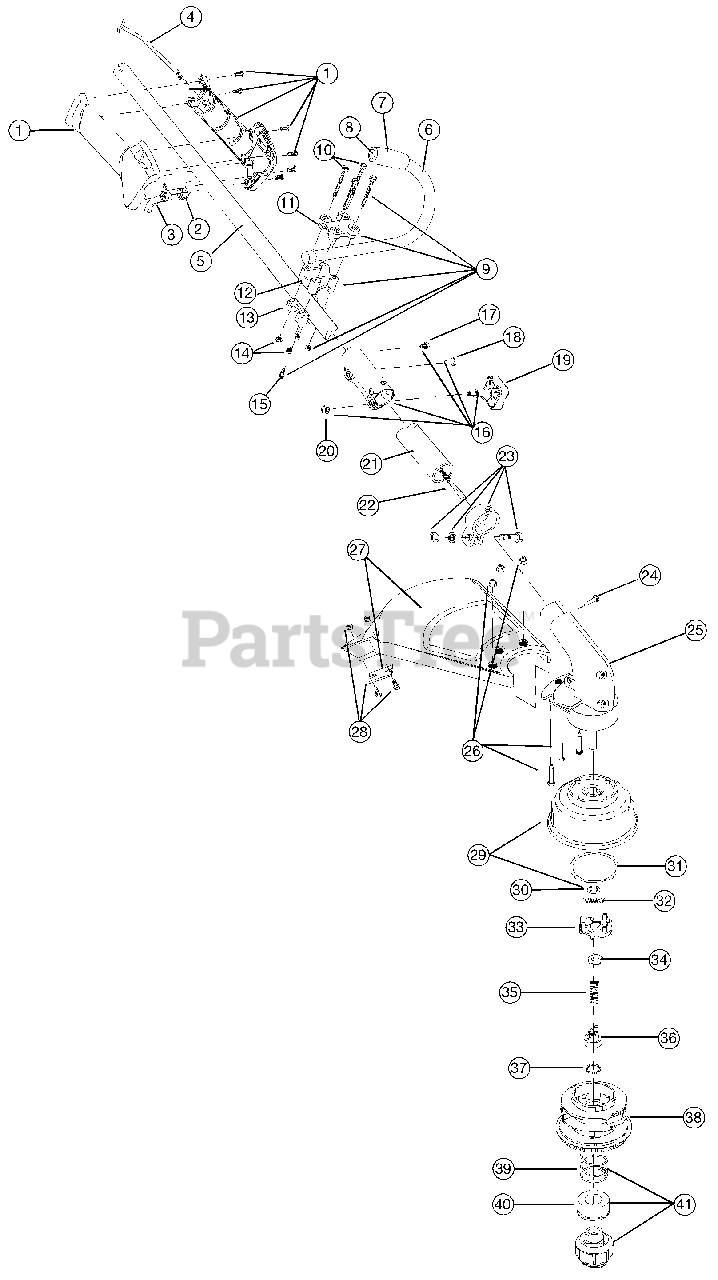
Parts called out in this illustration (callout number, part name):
1	Throttle Housing and Trigger Assembly
2	Throttle Trigger Spring
3	Throttle Trigger
4	Throttle Cable Assembly
5	Upper Drive Shaft Housing Assembly
6	J-Handle Assembly
8	Tube Closure
9	Handle Bracket Assembly
11	Upper Handle Clamp
12	Middle Handle Clamp
13	Lower Handle Clamp
15	Anti-Rotation Screw
16	EZ-Link Coupler
19	Adjustment Knob
20	Knob Retaining Nut
21	Lower Drive Shaft Housing Assembly
22	Lower Flexible Drive Shaft
23	Lower Clamp Assembly
24	Anti-Rotation Screw
25	Gearbox Assembly
26	Shield Mounting Hardware
27	Shield and Blade Assembly
28	Blade Assembly
29	Outer Spool Assembly
30	Retainer
31	Thrust Washer
32	Small Spring
33	Slider
36	Plunger
38	Inner Reel
39	Large Spring
40	Foam Seal & Washer
41	Bumb Head Knob Assembly
